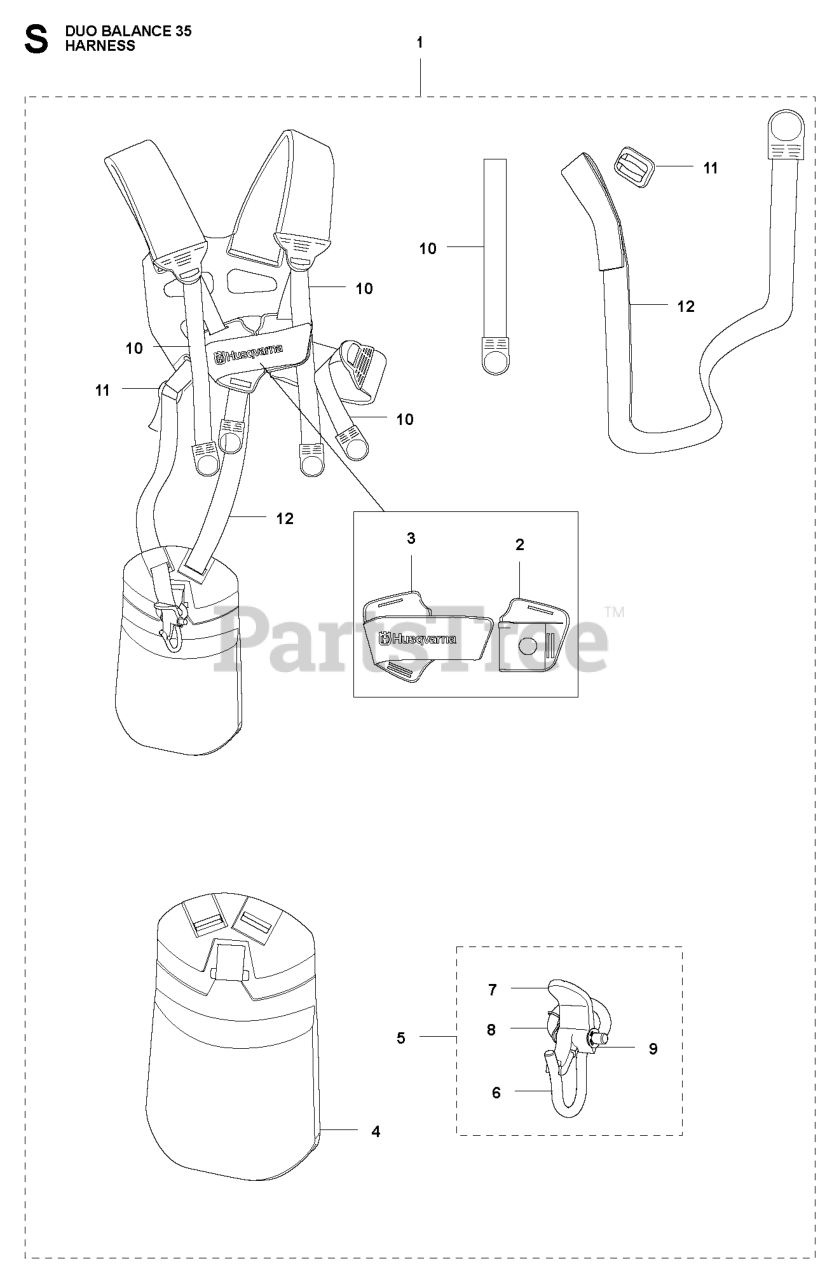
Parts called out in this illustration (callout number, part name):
1	Harness
1	Duo Balance Harness
2	FRONT PIECE
3	FRONT PIECE
5	HARNESS HOOK, COMPLETE
6	HOOK
7	CATCH *
8	SPRING LOCKING
11	RP CLIP
